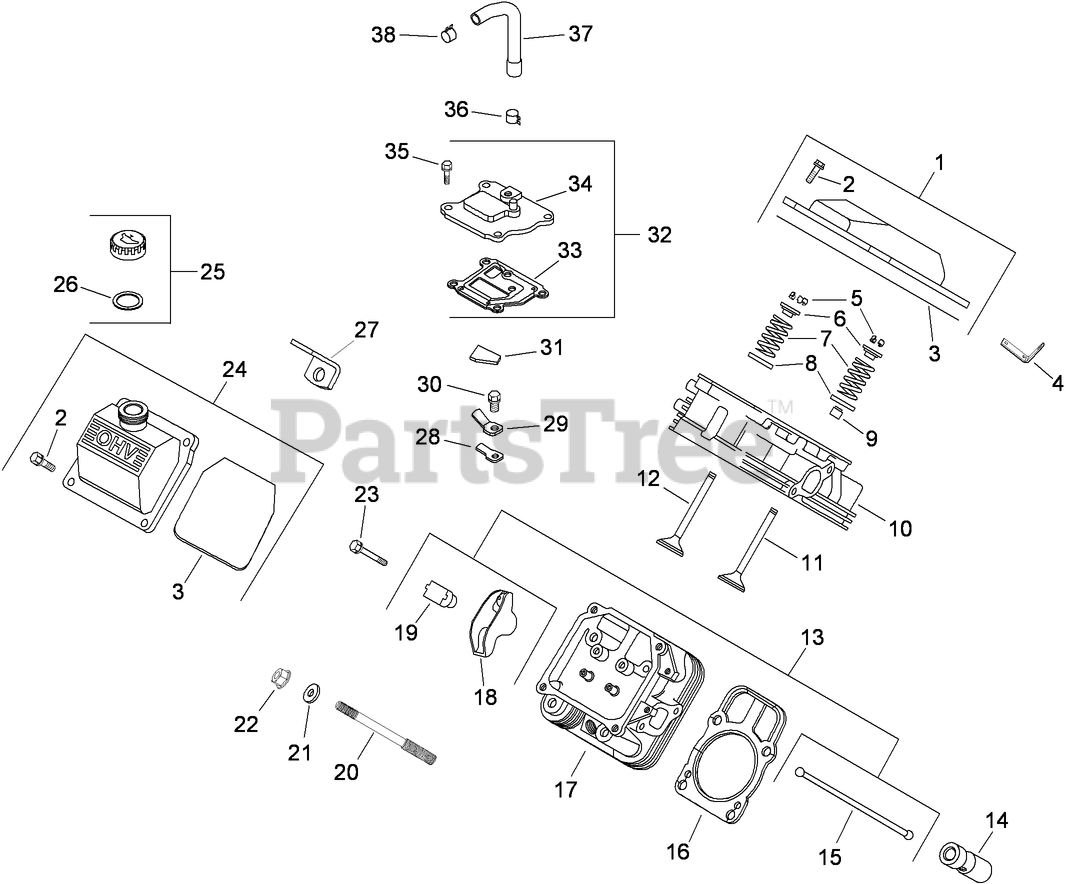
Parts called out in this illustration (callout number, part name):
1	PLAIN ROCKER COVER KIT (INCLUDES 2, 3)
2	SCREW-FLANGE (M6X1.0X30)
3	O-RING (VALVE COVER)
4	STRAP-LIFTING
5	RETAINER KIT
6	CAP-SPRING, VALVE
7	SPRING-VALVE
8	RETAINER-SPRING
9	SEAL-STEM, VALVE
10	CYLINDER HEAD No.1 ASM (INCLUDES 25 072 04-S)
11	VALVE-INTAKE (STD)
11	VALVE-INTAKE (.25)
12	VALVE-EXHAUST (STD)
12	VALVE-EXHAUST (.25)
13	VALVE TRAIN KIT (INCLUDES 15, 18, 19)
14	HYDRAULIC VALVE LIFTER KIT (INCLUDES 25 357 14-S)
15	ROD-PUSH
16	CYLINDER HEAD GASKET KIT
17	CYLINDER HEAD No.2 ASM (INCLUDES 25 072 04-S)
18	ARM-ROCKER
19	PIVOT-ARM, ROCKER
20	STUD (M8X1.25xM10X1.5x105MM)
21	WASHER-FLAT (8.6 MM)
22	NUT-FLANGE (M8X1.25)
23	SCREW-FLANGE (M6X1.0X34)
24	OIL FILL ROCKER COVER KIT (INCLUDES 2, 3)
25	OIL FILL CAP ASM (INCLUDES 26)
26	O-RING (DIPSTICK)
27	STRAP-LIFTING
28	REED-BREATHER
29	RETAINER-REED
30	SCREW-HHFTF (M5X.80X10)
31	FILTER-BREATHER
32	BREATHER ASM (INCLUDES 33, 34)
33	GASKET-BREATHER
34	COVER-BREATHER
35	SCREW-HHFTF (M6X1.0X20)
36	Clamp-Hose
37	HOSE, BREATHER
38	CLAMP-HOSE, SPRING (1/2)
